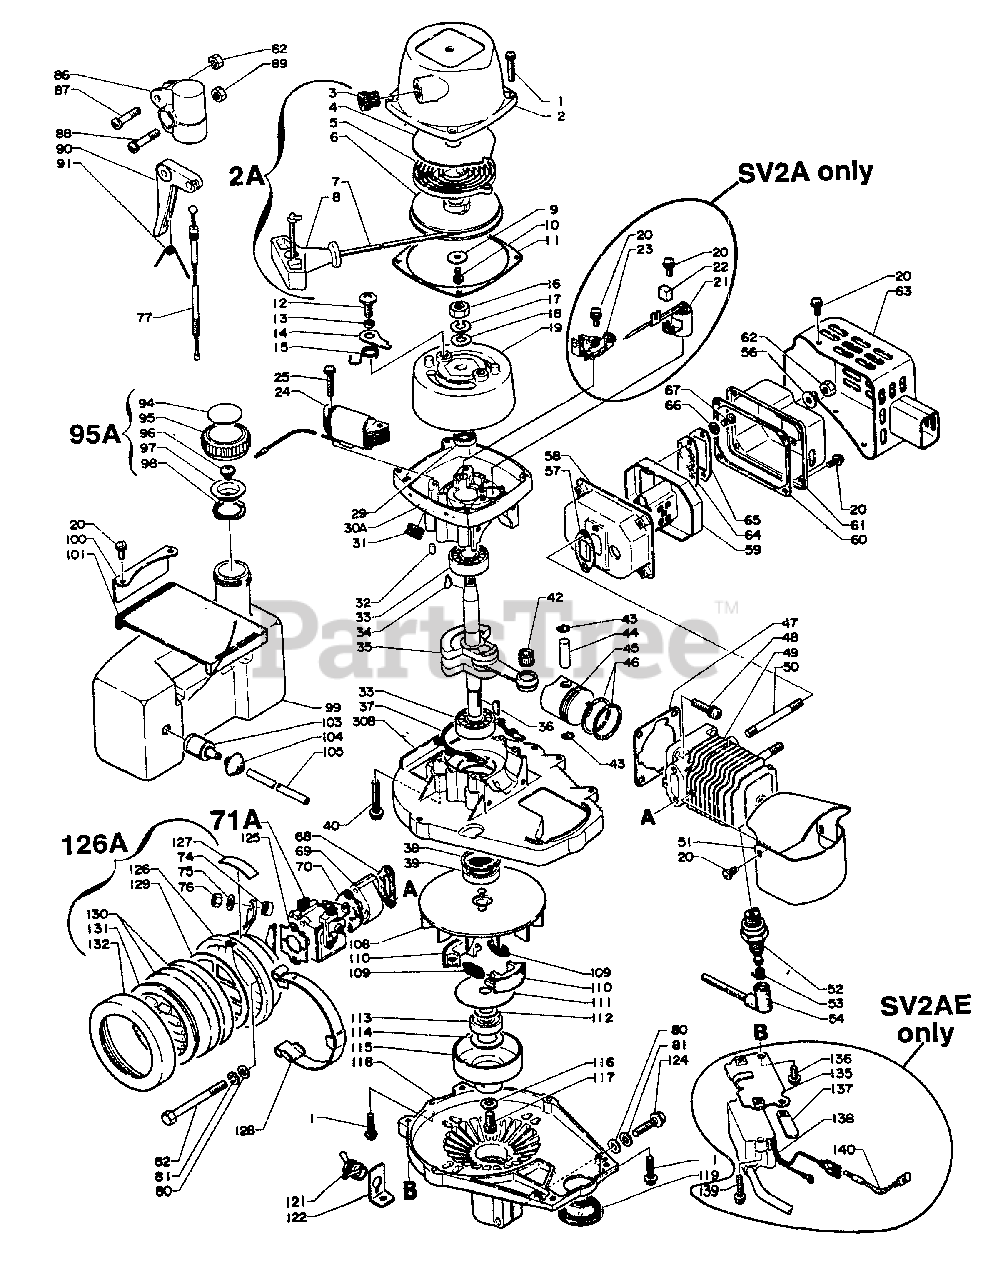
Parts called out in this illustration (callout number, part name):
1	SCREW - 4X20
2	CASE, STARTER
2A	STARTER ASSY
3	GUIDE, ROPE
4	PLATE, STARTER
5	SPRING, REWIND
6	REEL, ROPE
7	ROPE, STARTER - 3.5X850
8	GRIP, STARTER
10	SCREW - 4X10
11	GASKET, STARTER
12	SCREW
14	PAWL, STARTER
15	SPRING, RETURN
17	LOCKWASHER - 8
19	FLYWHEEL
20	SCREW - 4X10
21	CONDENSER
22	PAD, OIL
23	CONTACT POINT SET
24	COIL, IGNITION
24	COIL, EXCITER
25	SCREW - 4X25
29	SEAL, OIL
30A	CRANKCASE KIT
30B	CRANKCASE SET
31	GROMMET
31	BUSHING
32	PIN - LOCATING
33	BEARING, BALL - 6201
35	CRANKSHAFT ASSY
37	GASKET, CRANKCASE
38	RING, RETAINING - 32
39	SEAL, OIL
40	SCREW - 5X30
42	BEARING, NEEDLE
43	RING, RETAINING
44	PIN, PISTON
45	PISTON
46	RING, PISTON
47	GASKET, CYLINDER
48	SCREW - 5X20
49	CYLINDER
50	STUD
51	COVER, CYLINDER - BLACK
52	SPARK PLUG -- BM-6A
53	TERMINAL, SPARK PLUG CAP
54	CAP, SPARK PLUG
56	WASHER - 5
57	GASKET, EXHAUST
58	CASE, MUFFLER
59	SILENCER
60	GASKET, EXHAUST
61	LID, MUFFLER
62	LOCKNUT - 5
63	COVER, MUFFLER
64	SCREEN, SPARK ARRESTOR
65	RETAINER, SCREEN
66	LOCKWASHER - 4
67	SCREW - 4X8
68	GASKET, INTAKE
69	INSULATOR, INTAKE
70	GASKET, INTAKE
71A	CARBURETOR WA-59
75	WASHER - 6
77	CABLE, THROTTLE
80	WASHER - 5
81	LOCKWASHER - 5
86	BRACKET, TRIGGER
87	SCREW - 5X30
88	SCREW - 5X25
90	TRIGGER, THROTTLE
91	SPRING, TRIGGER
94	LABEL - FUEL MIX
95	CAP
95A	CAP ASSY
97	HOLDER, VENT
98	GASKET, CAP
99	TANK, FUEL
100	BRACKET, FUEL TANK
101	CUSHION
103	FILTER, FUEL
105	PIPE ASSY
108	FAN
109	SPRING, CLUTCH
110	SHOE, CLUTCH
111	PLATE, CLUTCH
112	WASHER, CLUTCH
113	BEARING, BALL - 6000
114	WASHER, CLUTCH
115	DRUM, CLUTCH
116	WASHER - 6
117	SCREW - 6X10
118	CASE, FAN
119	SEAL, DUST
120	CLIP
121	IGNITION SWITCH KIT
122	BRACKET, SWITCH
124	BOLT - 5X25
125	GASKET, INTAKE
126	CASE, AIR FILTER
126A	AIR CLEANER ASSY
127	LABEL - CHOKE
129	RETAINER, AIR FILTER
130	FILTER, AIR
131	COVER, AIR FILTER
132	COVER, AIR FILTER
135	BRACKET, IGNITION COIL
136	SCREW - 5X10
137	CLIP
138	COIL, IGNITION
139	SCREW - 4X16
140	LEAD - GROUND
